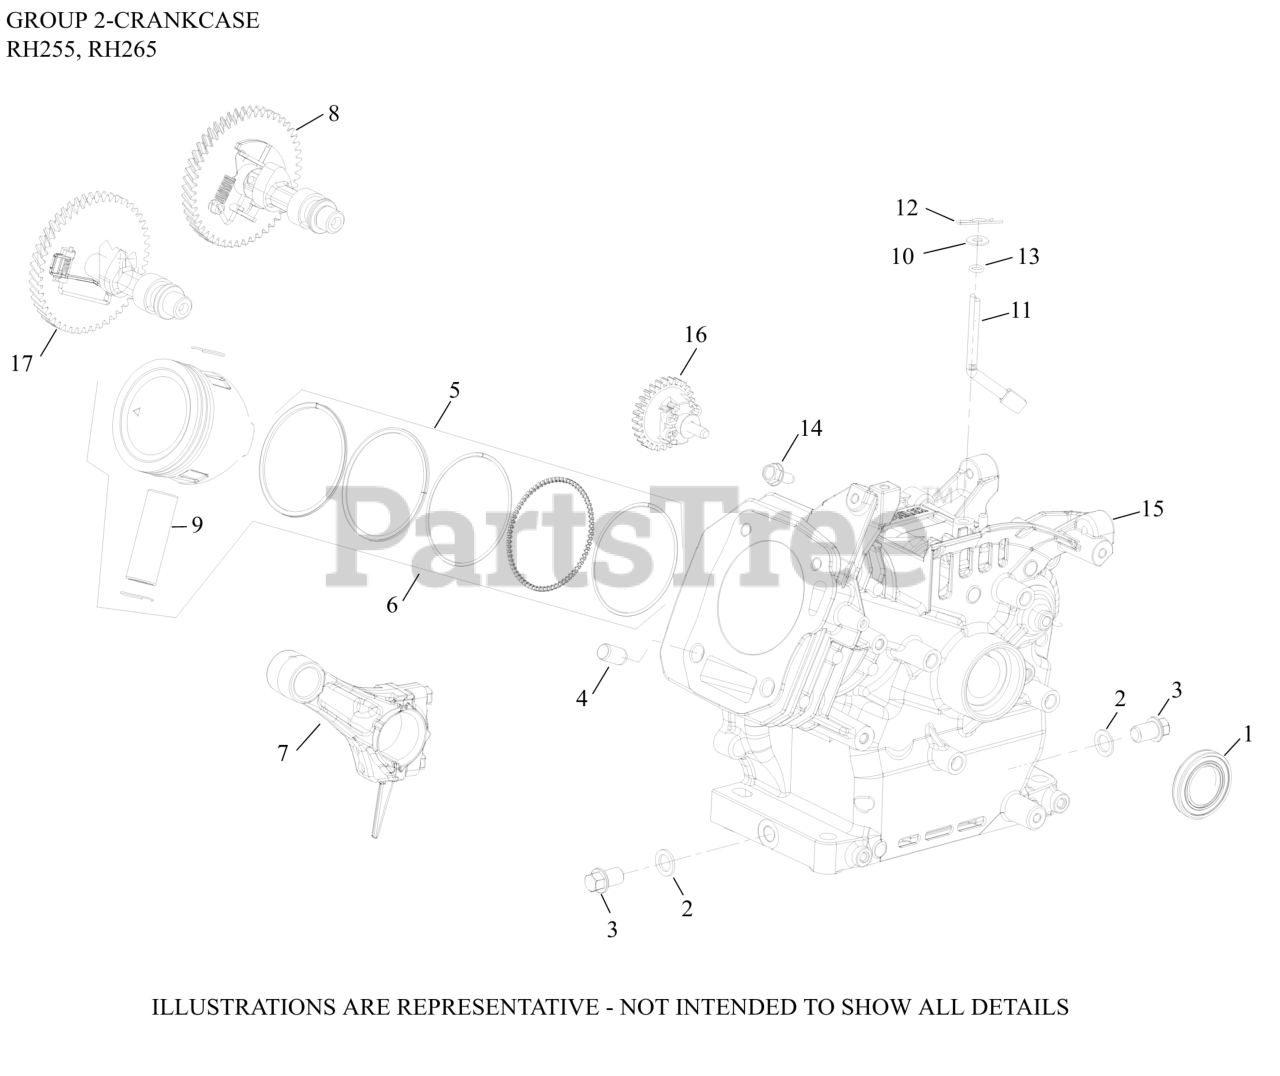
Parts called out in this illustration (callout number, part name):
2	WASHER, DRAIN PLUG
3	KIT, DRAIN PLUG
6	KIT, PISTON (STD)
7	ROD, CONNECTING ASSEMBLY
9	PIN, PISTON
10	WASHER, FLAT (DIA 13mm O.D.)
11	CROSS SHAFT
12	CLIP, GOVERNOR SHAFT
16	GOVERNOR ASSEMBLY
17	CAMSHAFT, ASSEMBLY
